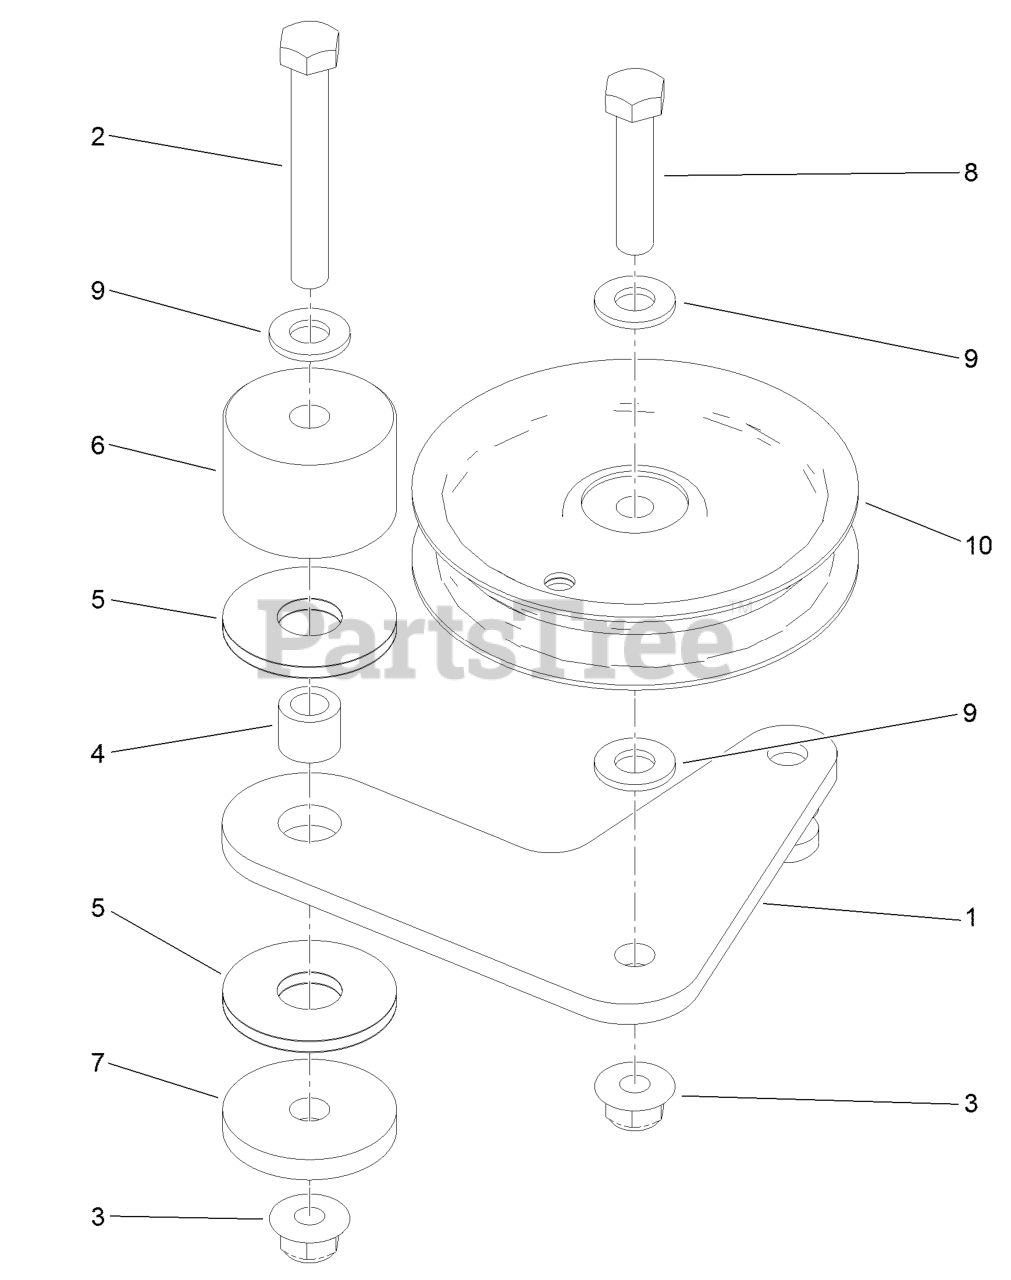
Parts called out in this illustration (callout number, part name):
1	PLATE-IDLER
2	SCREW-HH
3	NUT-HF, NI
4	BUSHING-LEVER, LIFT
5	WASHER-FRICTION, COMPOSIT
6	HUB-IDLER
7	WASHER-PLAIN
8	SCREW-HH
9	WASHER-FLAT
10	PULLEY-IDLER
